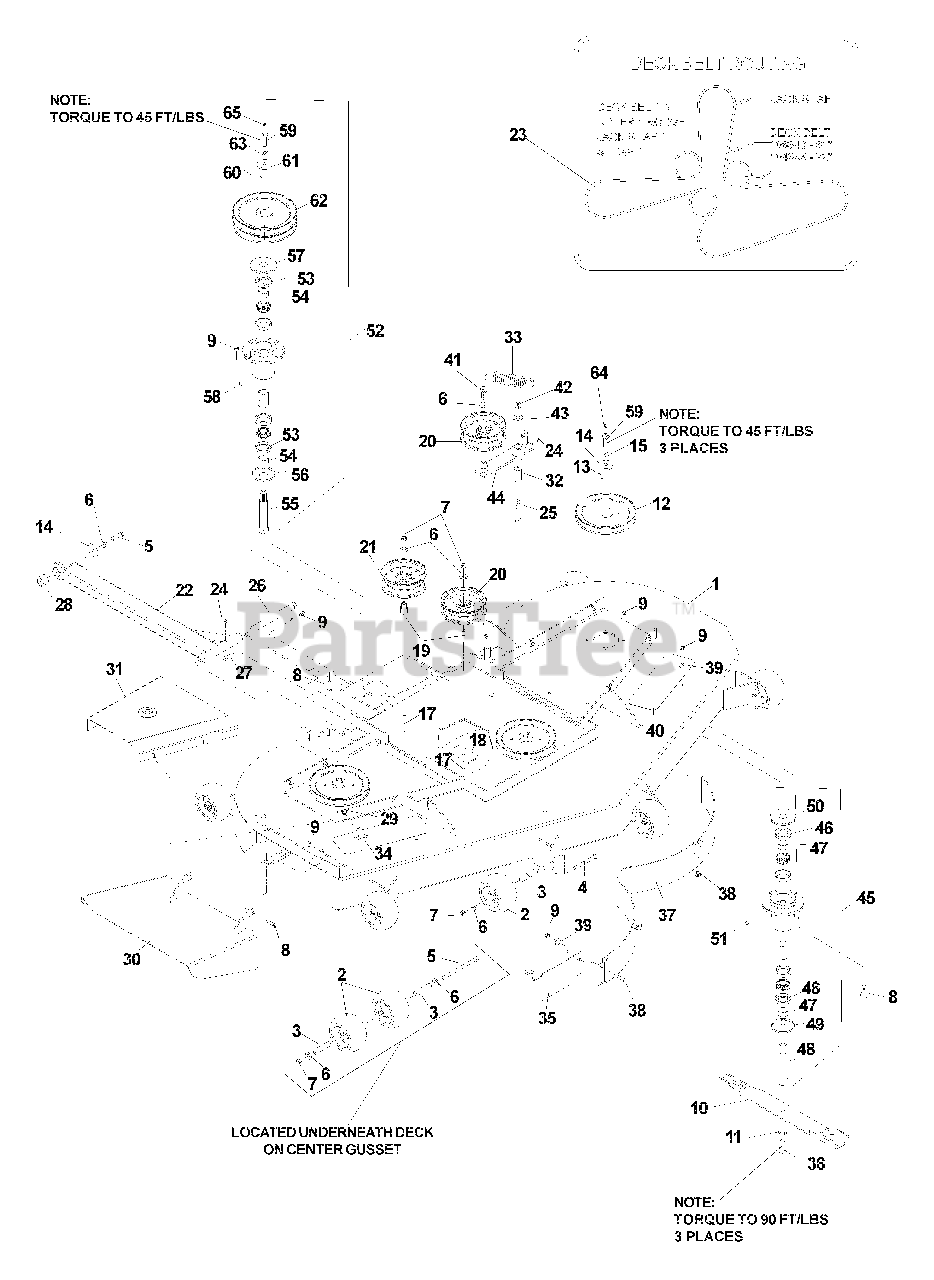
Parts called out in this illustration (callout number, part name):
1	72" Deck w/decals
2	Anti-scalp roller
4	Bolt, 3/8-16 x 3 1/2
5	Bolt, 3/8-16 x 6, Gd. 8
6	Washer, 3/8
7	Nut, 3/8-16, centerlock
8	Bolt, 5/16-18 x 1
9	Nut, 5/16-18, centerlock
10	Blade, 25"
11	Washer, 5/8, spring
12	Pulley
13	Key, 1/4" sq. x 1 1/8"
14	Washer, heavy
15	Lockwasher, 7/16
16	Bolt, 7/16-20 x 1 1/2
17	Bolt, 3/8-16 x 2 1/2
18	Pad
19	Bushing, idler
20	Pulley, idler
21	Pulley, idler (tall)
22	Strut, right
23	72" Deck belt
24	Zerk
25	Bolt, 1/2-13 x 3 1/4, Gd. 5
27	Bolt, 5/16-18 x 3/4
28	Spacer, strut
30	Chute, discharge
31	Shield, belt, right
32	Bushing, pivot
34	Knob w/stud
35	Baffle, center
36	Bolt, 5/8-18 x 2, Gd. 8
37	Baffle, center curved
38	Bolt, 5/16-18 x 5/8, carriage
39	Washer, 5/16
40	Pad, abrasive
41	Bolt, 3/8-16 x 1, ser.
42	Nut, 1/2-13, nyloc
43	Washer, 1/2
45	Cutter housing, complete
46	Shaft seal
48	Mini spindle
49	Dust cap, bottom
50	Dust cap, top
51	Grease popet
52	Jackshaft assembly, lower
53	Shaft seal
55	Jackshaft spindle
56	Dust cap, bottom
57	Dust cap, top
58	Grease popet
59	Bolt, 7/16-20 x 1 1/2, GD. 5, special
60	Key, 1/4" sq. x 1 1/8"
61	Washer, heavy
63	Lockwasher, 7/16
64	Zerk
65	Zerk, 90°
